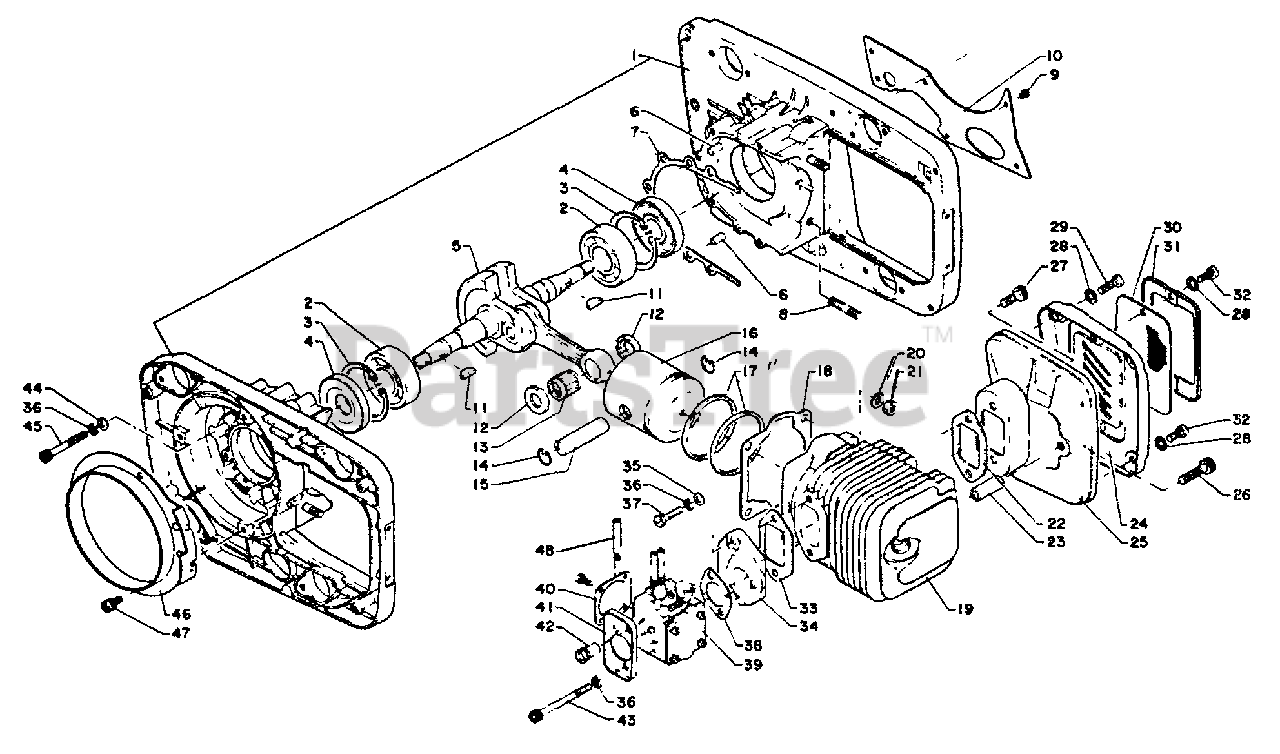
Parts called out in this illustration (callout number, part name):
1	CRANKCASE KIT
2	BEARING, BALL BB6204
3	RING, RETAINING - 47
4	SEAL, OIL
5	CRANKSHAFT ASSY
6	PIN, LOCATING 5×10
7	GASKET, CRANKCASE
8	STUD
9	RIVET (3.5 MM)
10	SEAL, DUST
11	KEY, WOODRUFF - 3×14
12	SPACER, PISTON
13	BEARING, NEEDLE
14	RING, SNAP
15	PIN, PISTON
16	PISTON
17	RING, PISTON
18	GASKET, CYLINDER
19	CYLINDER
20	WASHER 6.5×11.5×0.8
21	NUT, HEX M6
22	GASKET, EXHAUST
23	MUFFLER SPACER
24	LID, MUFFLER
25	MUFFLER
26	SCREW - 6×30
27	SCREW - 6×15
28	LOCKWASHER - 5
29	SCREW 5×16
30	SCREEN, SPARK ARRESTER
31	RETAINER, SCREEN
32	SCREW 5×8
33	GASKET, INTAKE
34	INSULATOR, INTAKE
35	WASHER
36	WASHER, SPRING 5
37	BOLT 5×30
38	GASKET, INTAKE
39	CARBURETOR - SDC-76
40	CARBURETOR COVER
41	CARBURETOR ADAPTER
42	GROMMET
43	BOLT 5×55
44	WASHER
45	BOLT 5×40
46	SEAL, DUST
47	SCREW 5×10
48	TUBE
